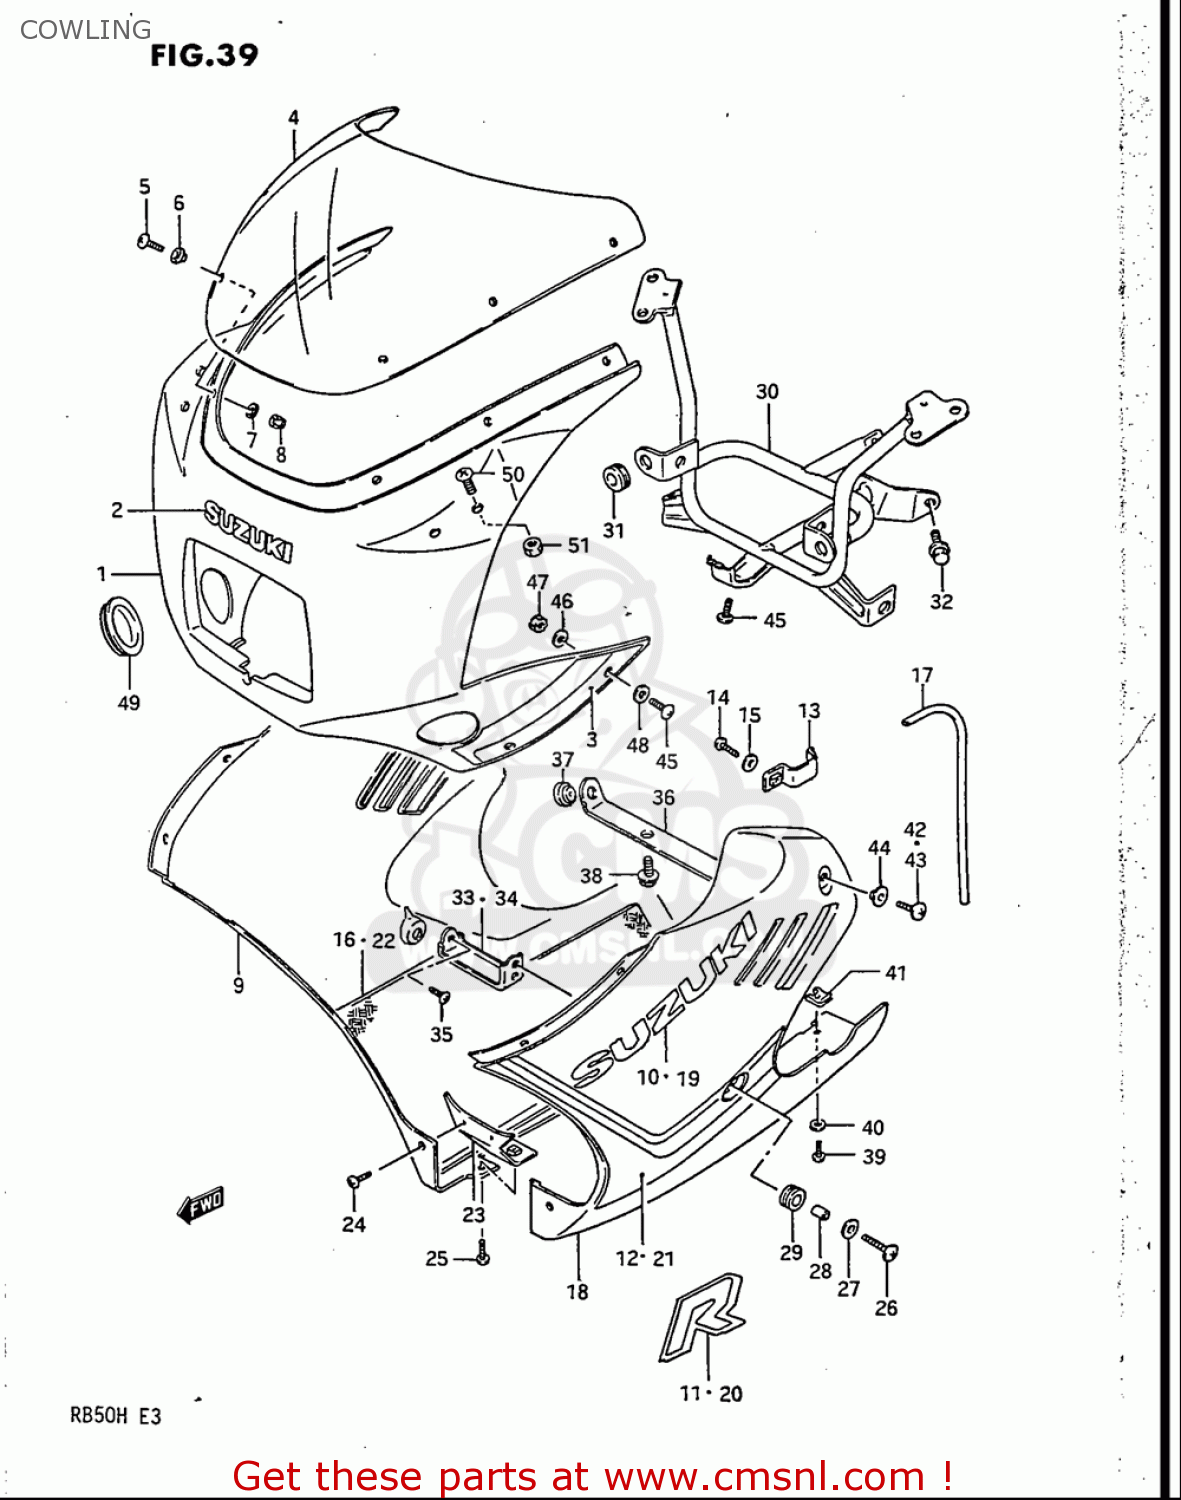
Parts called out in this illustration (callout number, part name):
1	BODY,COWLING
2	EMBLEM(WHITE)
3	TAPE SET,COWLING,FRONT
4	WINDOW,COWLING
5	SCREW
6	CUSHION
7	WASHER
8	NUT
9	COVER SET,COWLING,R
10	EMBLEM
11	EMBLEM,COWLING SIDE
14	SCREW
15	WASHER
17	HOSE
18	COVER SET,COWLING,L
19	EMBLEM
20	EMBLEM,COWLING SIDE
23	BRACKET,COWLING LWR
24	SCREW
25	SCREW
26	SCREW
27	WASHER(6.5X18X1)
29	CUSHION
30	BRACE,COWLING
31	CUSHION
32	BOLT
33	BRACE,COWLING LWR,R
34	BRACE,COWLING,LOWER,LEFT
35	SCREW
36	PLATE,COWLING SUPPORT
37	CUSHION
38	BOLT
39	SCREW
40	WASHER(5.2X16X1)
41	NUT
42	SCREW 6X12
43	SCREW(6X16)
44	WASHER
45	SCREW
46	WASHER
47	NUT
48	WASHER
49	GROMMET,FAIRING
50	SCREW 6X12
51	NUT
